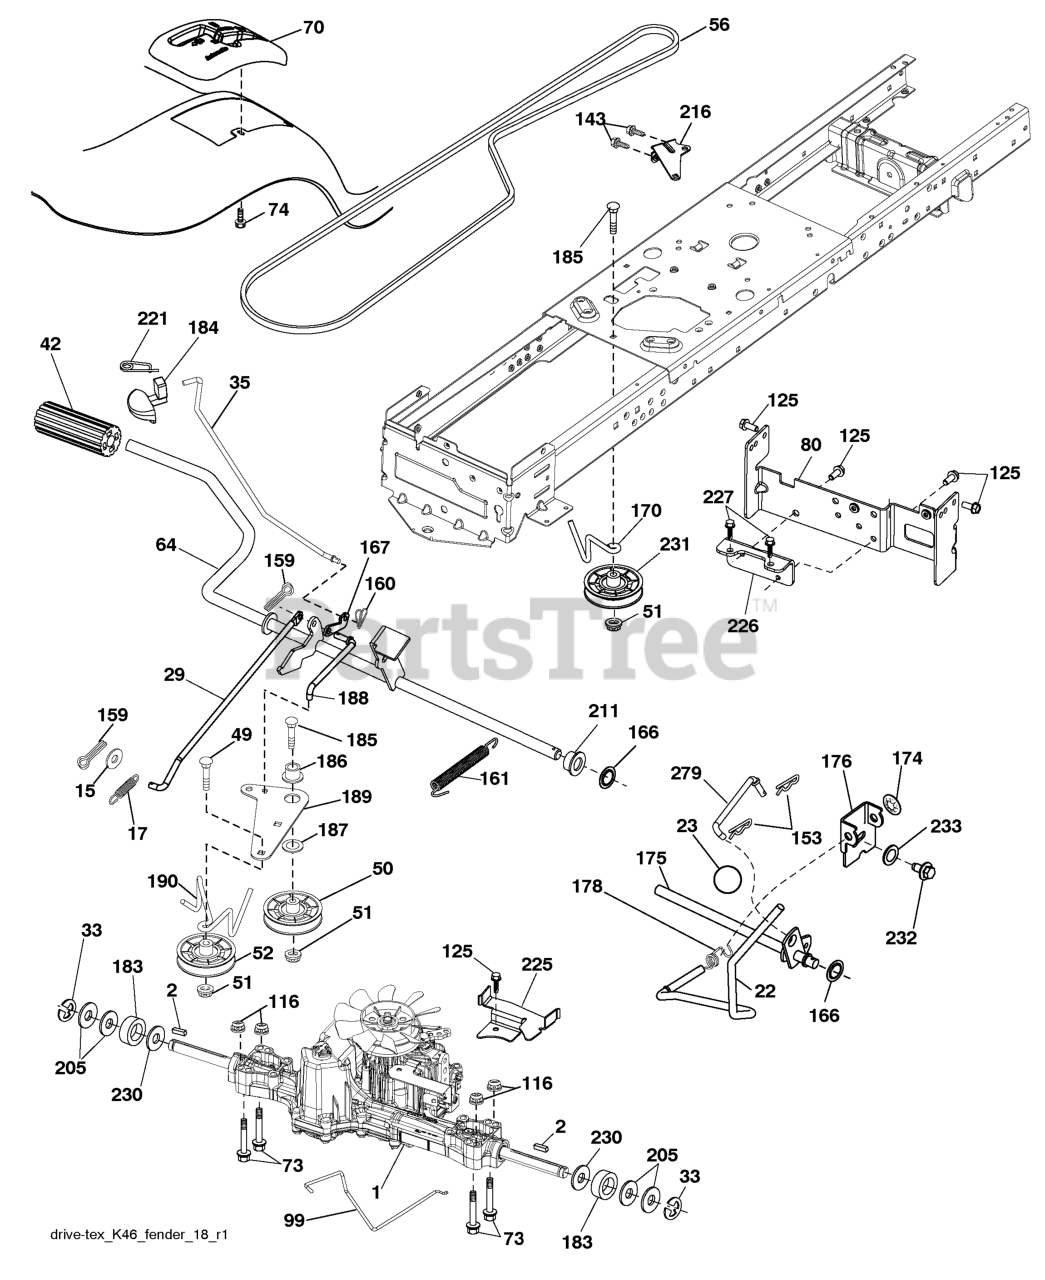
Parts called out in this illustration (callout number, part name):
1	Transaxle, Tufftorq K46BA (Internal Parts Not Available)
2	SQUARE KEY
15	WASHER
17	SPRING.BRAKE.K46.GREEN
22	ROD.SHIFT.FENDER.TLT.2006
23	KNOB.DELUXE.(PISTOL.GRIP).BLAC
29	ROD.BRAKE.K46
35	ROD.CNTRL.PARK.PREDATOR.LT.TEX
42	PEDAL COVER T
50	IDLER.FLAT.910.OFFSET
51	NUT LOCK FLG 3/8-16 UNC
52	IDLER.V-GROOVE.910.OFFSET
56	V-BELT.MOWER.92.40.42/K46
64	SHAFT.ASM.PEDAL.BRAKE.
70	CONSOLE SHIFT
73	BOLT HEX 5/16-18 GR 5
74	SCREW.HI-LO.CONSOLE
80	STRAP TORQUE
99	ROD.SPRING.BYPASS.K46.LT.Z
116	NUT LOCK HEX FLANGE 5/16-18
125	SCREW
143	Screw THDROL 5/16-18
153	RETAINER M
159	COTTER PIN
160	RETAINER CLIP
161	SPRING, RETURN LT
166	NUT.PUSH.625
167	LATCH.BRAKE.SPRING
170	KEEPER.CENTER SPAN.1.688
174	NUT.PUSH.500.2006
175	SHAFT.ASM.SHFT.T2.TLT
176	ARM.CLEVIS.ROD.SHIFT
178	SPRING.SHIFT.GT2006
183	SPACER AXLE
184	HANDLE PARKING BRAKE
186	SPACER.RETAINER
187	WASHER 12/32X2X10GA
188	RP.LINK.CLUTCH.GROUND.DRIVE
189	BELLCRANK.GROUND.DRIVE.TEX.
190	KEEPER.BELLCRANK.DRIVE
211	BUSHING.SHAFT.BRAKE.HAND
216	BRACKET.PULLEY.IDLER.W/TEX
221	RETAINER.SPRING.CLIP.H
225	KEEPER.BELT.TRANSAXLE.K46
226	BRACKET.MOUNT.TORQUE.K46.TLT
227	SCREW.THDROL.5/16-18X3/4.TTY
230	WASHER.HARDENED
231	IDLER.V-GROOVE.1.688.OFFSET
232	BOLT FIN HEX 7/16-14 X 1
233	WASHER SERRATED
279	LINK.SHIFT.
